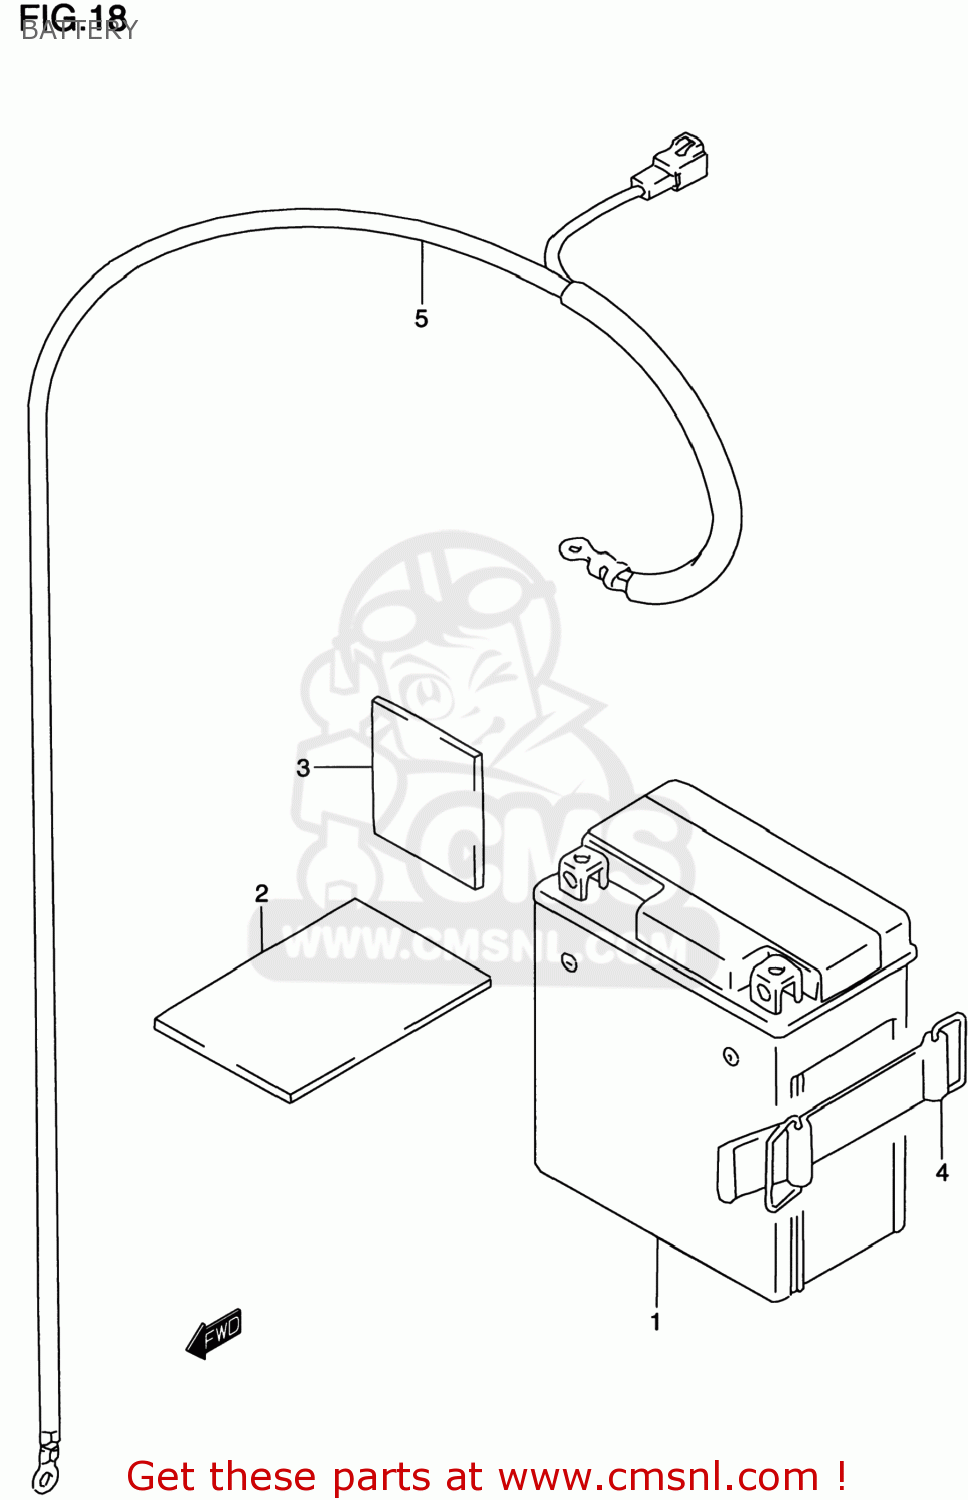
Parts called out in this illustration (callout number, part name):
1	BATTERY ASSY(YTX7L-BS,12V6AH)
2	PROTECTOR(170X95X3.0)
3	PROTECTOR(170X95X3.0)
4	BAND
5	WIRE,BATTERY MINUS
